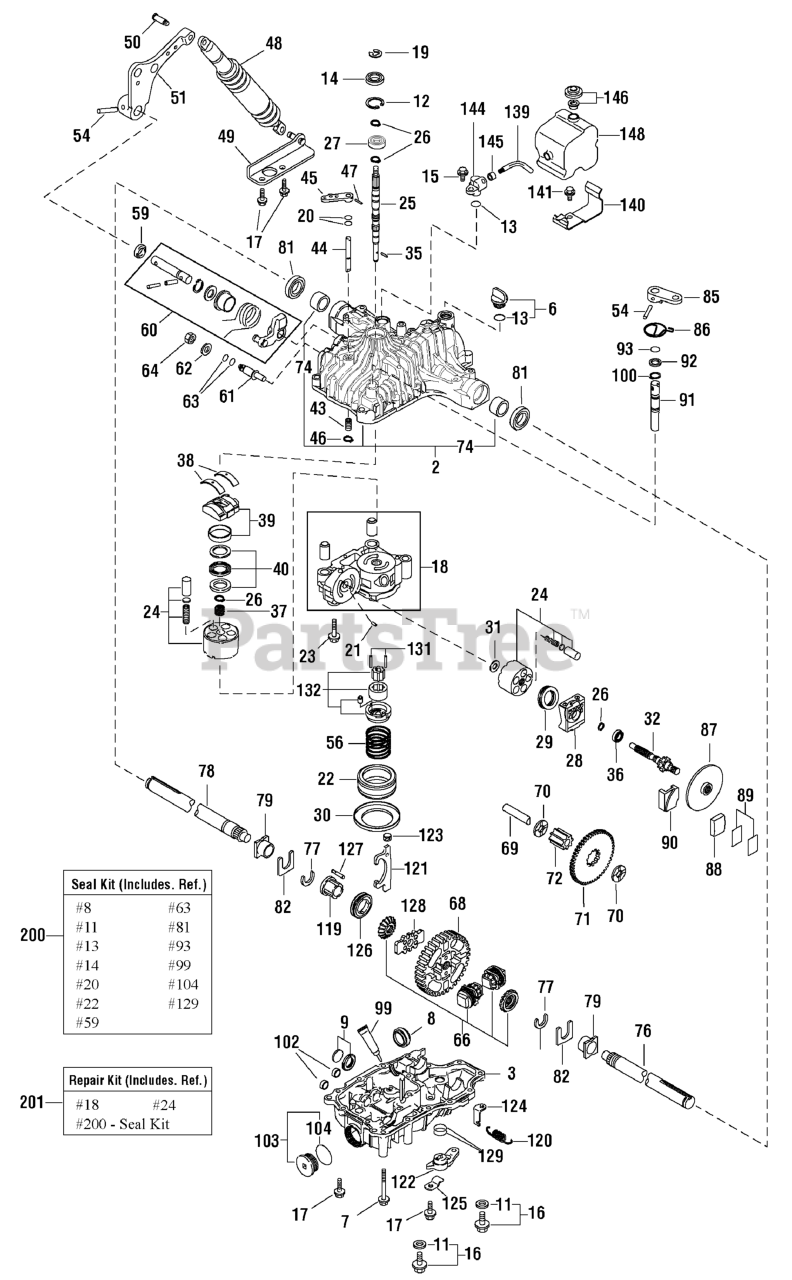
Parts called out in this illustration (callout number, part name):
1	TRANSAXLE, Tuff Torq K66L
2	*KIT, Upper Case
3	HOUSING, Lower
6	CAP, M20B
7	CAPSCREW, 8 x 75
9	MAGNET, Complete
11	WASHER, Seal, 10
12	RING, Snap, C 35
15	BOLT, 8 x 20
16	*KIT, Drain Bolt
17	SCREW, Tapping, 8 x 30
18	CASE, Center
19	E-RING, 15
21	PIN, 3 x 9.8
23	BOLT, 10 x 65
24	*KIT, Cylinder Block
25	*SHAFT, Pump
26	RING, Snap, S15
28	*HOUSING, Motor
29	BEARING, Thrust
30	*CAP, Filter
31	WASHER, 12 x 24 x 1
32	MOTOR SHAFT/GEAR (10T)
35	PIN, 3 x 13.8
36	BEARING, 6302DUC3
37	SPRING, Pump
38	BEARING, Thrust
39	*ASSEMBLY, Swash Plate
40	*KIT, Thrust Bearing
44	*SHAFT, Bypass
45	LEVER, Bypass
46	RING, Snap, 10
48	SHOCK ABSORBER, K65
51	CONTROL LEVER A
54	PIN, Roll, 6 x 40
56	*CHARGE SPRING
60	*KIT, Control Shaft
62	WASHER, 12
66	*KIT, Differential Gear
68	*GEAR, Final
69	*SHAFT, Final Pinion
70	WASHER, 15 x 35 x 3.2
71	GEAR, Reduction
72	PINION, Final
74	BUSHING, 25.4
76	*SHAFT, Axle, Left
77	RING, Retaining, 23
78	*SHAFT, Axle, Right
79	BUSHING, 25.4
81	SEAL, S25.4 x 42 x 8
82	WASHER, Thrust
85	LEVER, Brake
86	SPRING, Brake Return
87	DISK, Brake
88	*SHOE, Brake
89	KIT, Shim
90	BRAKE ACTUATOR
91	*SHAFT, Brake
92	WASHER, 16 x 23 x 1.6
99	*SEALANT
100	RING, Snap
103	*CAP KIT
120	SLIDER, Differential Lock
121	*FORK, Differential Lock
122	*LEVER, Differential Lock
123	*LEVER PIVOT
124	HOOK, Spring
125	PLATE, Arm
126	SLIDER, Differential Lock
127	*PIN, Differential Lock
128	*PLATE, Differential Lock
132	*KIT, Charge Pump
139	*PIPE
140	*BRACKET, Tank
141	SCREW, Tapping, 8 x 20
144	*FITTING
148	TANK, Reservoir
200	SEAL KIT
201	*KIT, Repair
